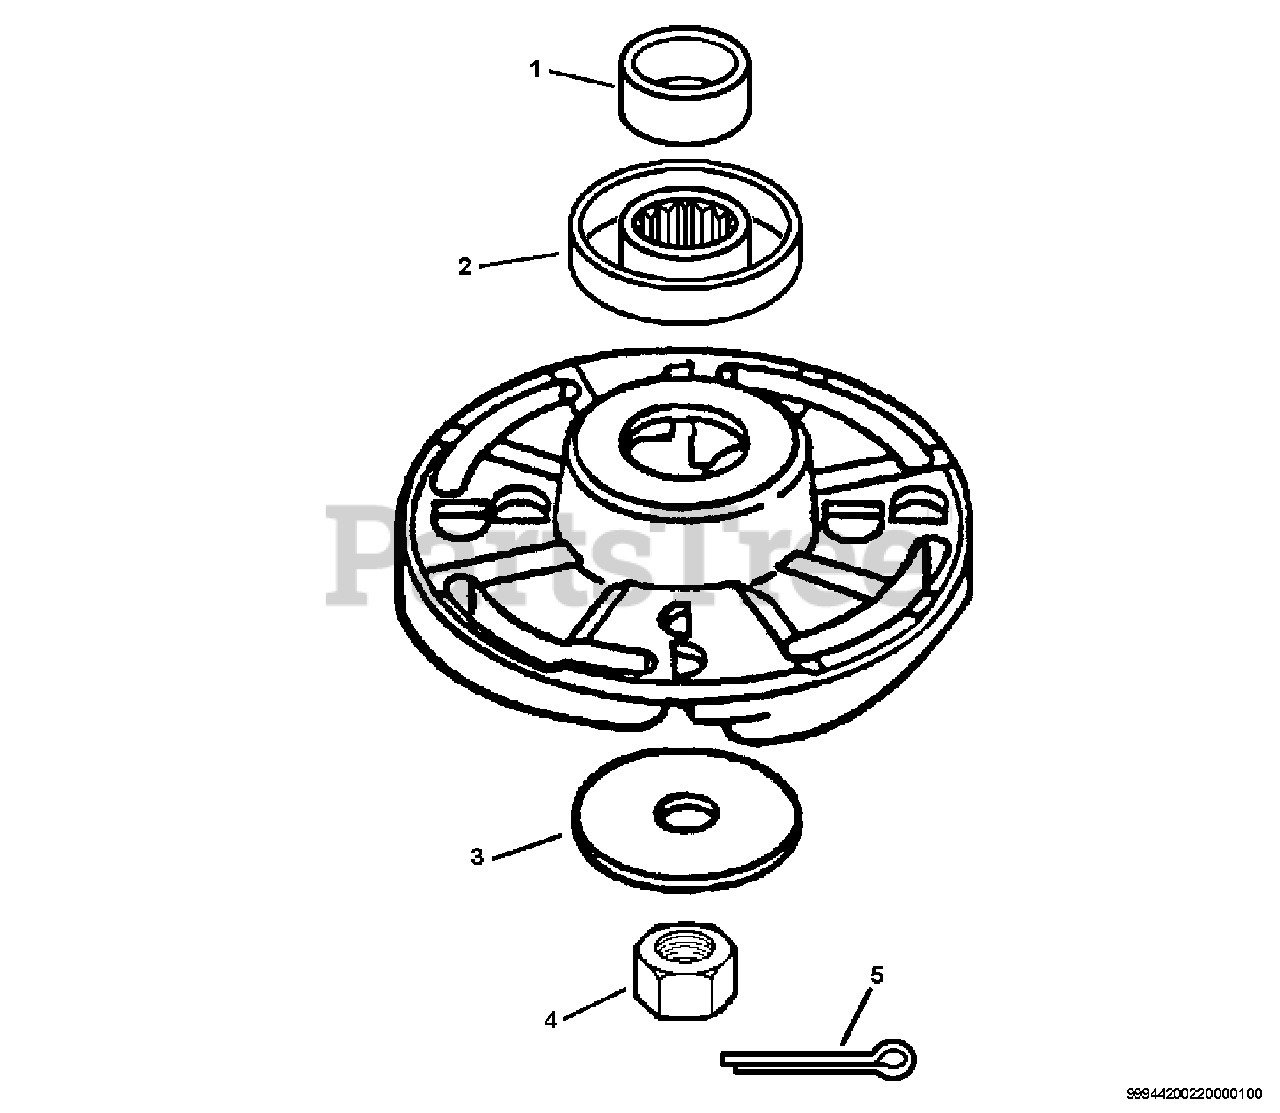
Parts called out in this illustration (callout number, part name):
2	ADAPTOR, BLADE - UPPER
3	ADAPTOR, BLADE - LOWER
4	NUT - 10 -- LEFT HAND
5	PIN, SPLIT - 2X22
